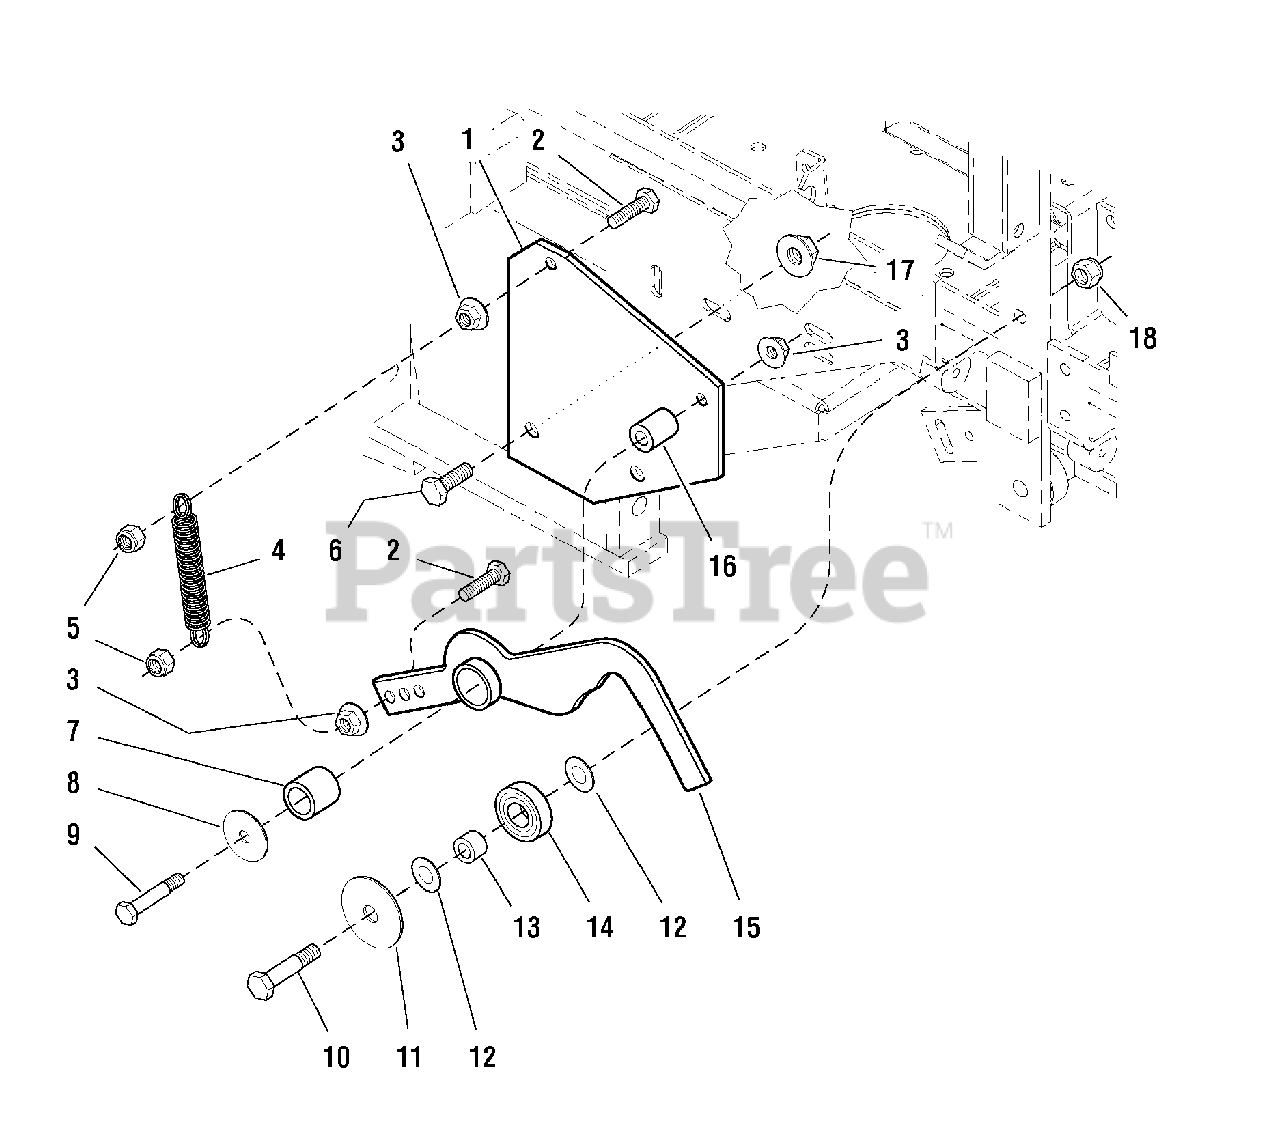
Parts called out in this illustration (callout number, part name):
1	NEUTRAL RETURN MOUNT PLATE
2	CAPSCREW, Hex Hd, 5/16-18 x 1-1/4 TFL
3	NUT, Hex, Serrated Flange, 5/16-18
4	SPRING, Extension
5	NUT, Hex, Nylon Lock, 5/16-18
6	CAPSCREW, Hex Hd, 3/8-16 x 3/4
7	BUSHING, Brass
8	WASHER, 5/16 Fender
9	CAPSCREW, Hex Hd, 5/16-18 x 1-3/4
10	CAPSCREW, Hex Hd, 3/8-16 x 1-3/4
11	WASHER, 3/8 x 2
12	WASHER, 3/8
13	INSERT, Bearing
14	BEARING, BALL 11/16X1-9/16X15/32
15	NEUTRAL RETURN LEVER
16	SPACER, .32 x .75 x 1.06
17	NUT, Hex, Serrated Flange, 3/8-16
18	NUT, Hex, Nylon Lock, 3/8-16
